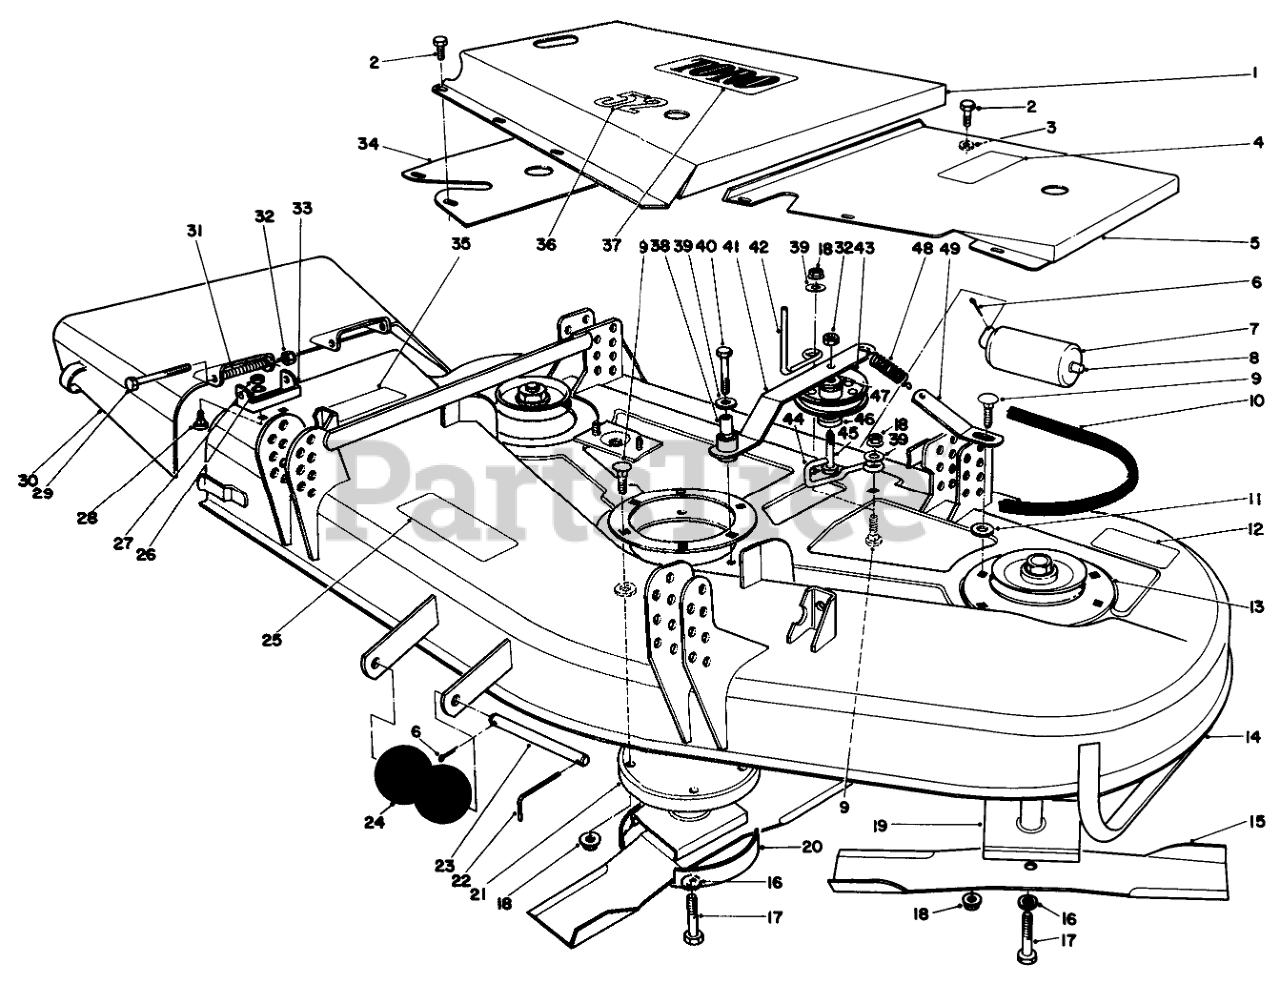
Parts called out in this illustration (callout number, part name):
1	CENTER COVER WA 52 R
2	SCREW-HHFTF
3	WASHER-FLAT
4	DECAL
5	Cover
6	PIN-COTTER
7	ROLLER-DECK
8	SHAFT-ROLLER, REAR
9	SCREW-CARR
10	V-BELT
11	WASHER-FLAT
12	DECAL-CAUTION, BLADE
13	SUPPORT-DECK, RING
14	Deck Assembly
15	Blade
16	WASHER-LOCK
17	SCREW-BLADE
18	NUT-HF
19	SPINDLE ASM
20	Cup-Scalp
21	HOUSING - SPINDLE ASM
22	PIN-SPECIAL
23	SHAFT-ROLLER
24	ROLLER
25	Decal-Caution
26	WASHER-LOCK
27	NUT-HEX
28	SCREW-CARR
29	SCREW-HH
30	Deflector
31	SPRING
32	NUT-HEX
33	Bracket-Pivot
34	Cover
35	DECAL-CAUTION, DEFLECTOR
36	DECAL
37	DECAL
38	SLEEVE
39	WASHER-FLAT
40	SCREW-HH
41	Arm-Idler
42	ROD-BELT
43	PULLEY-IDLER
44	GUIDE-BELT
45	Bolt-Special
46	BUSHING-PULLEY
47	WASHER-FLAT
48	SPRING-EXTENSION
49	PLATE-SPRING
